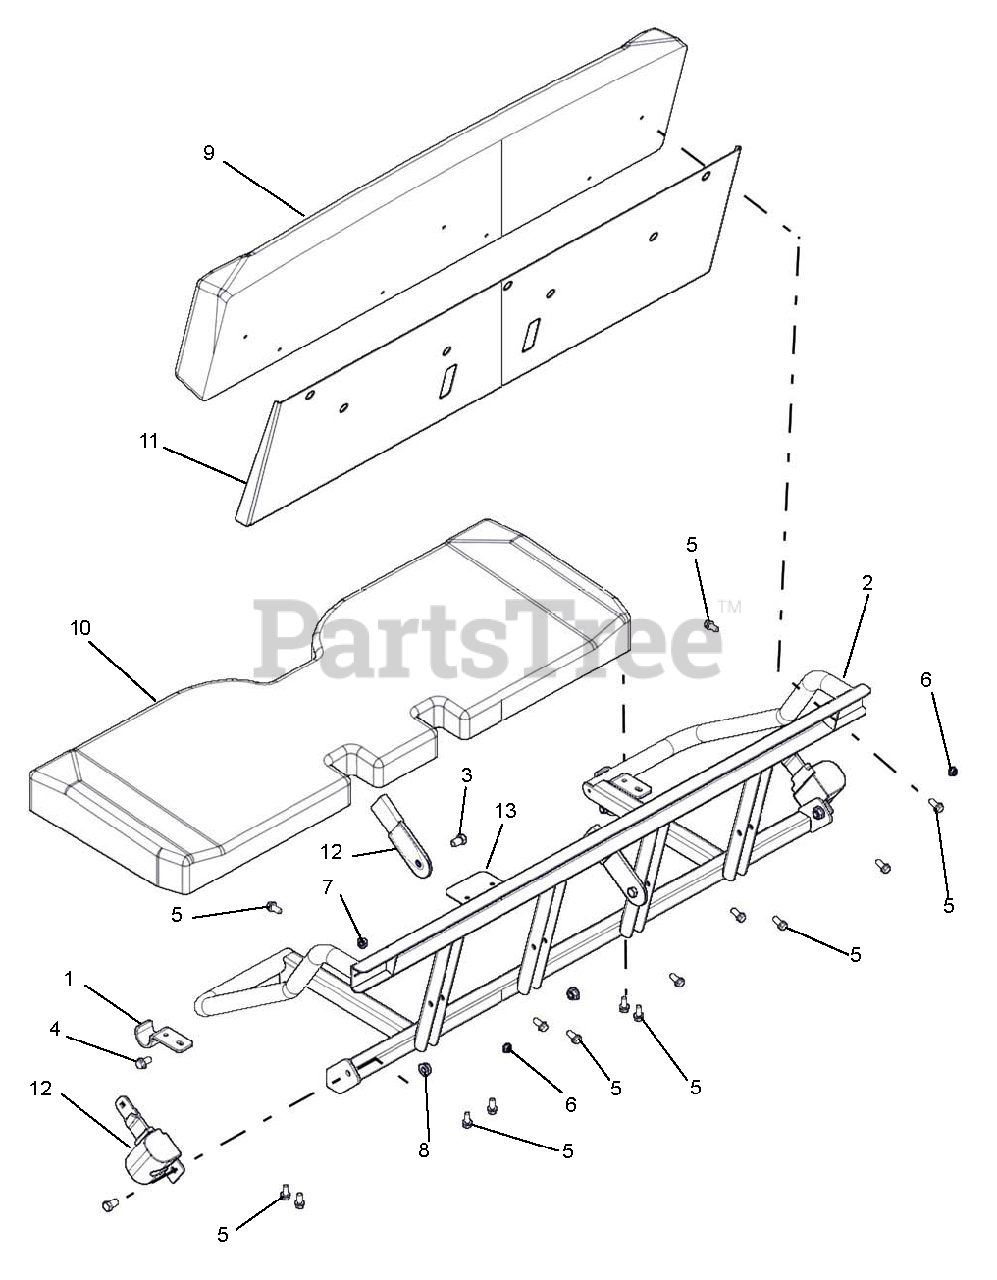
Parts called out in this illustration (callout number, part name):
1	SEAT PIVOT PLATE
2	SEAT FRAME, TREKER
3	@BLT-HEX .44-14X1.00 GR5 YWZC
4	HFSS 3/8-16X3/4 LG
5	BLT-SERHFWH .312-18X.75 YWZC
6	@NUT-LK-TOP-FLG .31-18 YWZC
7	@NUT-LK-TOP-FLG .38-16 YWZC
8	NUT-LK-TOP .437-14 GR C PL
9	SEAT BACK, BENCH
10	SEAT BOTTOM
11	SEAT BACK PANEL, BLACK
12	ASSY, SEAT BELT
13	SEAT BOTTOM PLATE
